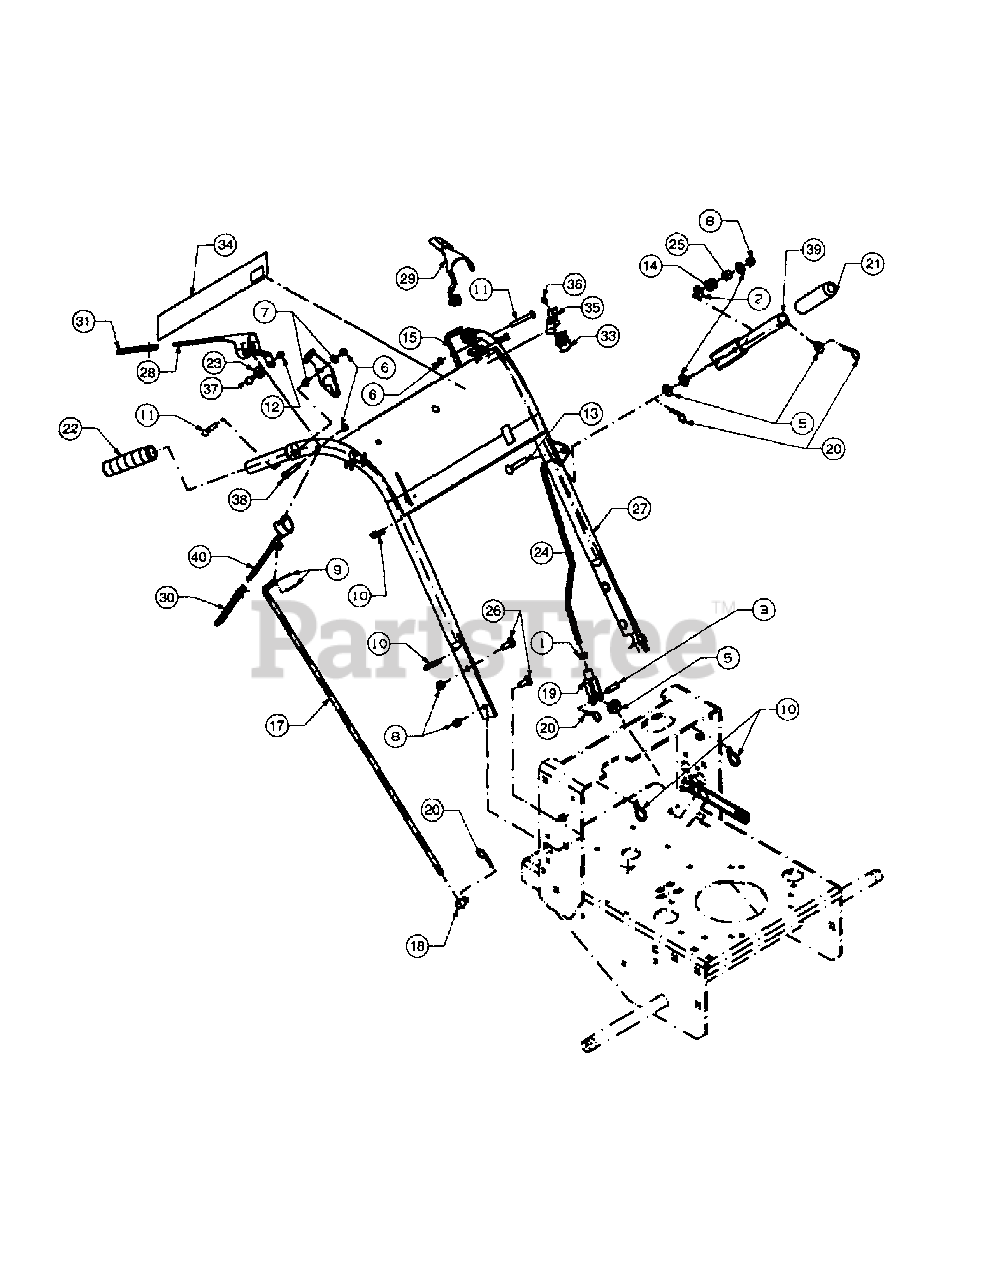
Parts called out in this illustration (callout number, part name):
1	Hex Nut, 3/8-16
2	Flat Washer, 3/8 Zinc
3	Clevis Pin, 3/8 x 1-1/8 Zinc
4	Grip, Neutral Latch, 1.25"
5	Flat Washer, 3/8 Zinc
6	Nylock Nut, 5/16-18
7	Flat Washer, 5/16 Zinc
8	Lock Nut, Nylon Insert, 3/8-16
9	Cotter Pin, 3/32 x 3/4, Zinc
10	Cable Tie, 3/16 x. 05 x 7.4
11	Hex Cap Screw, 5/16-18 x 2
12	Lock Nut, Nylon Insert
13	Carriage Bolt, 3/8-16 x 2
14	Spring, .850 OD x 1
15	Neutral Latch, Left Hand
15	Neutral Latch, Right Hand
17	Steering Control Rod
18	Joint Swivel
19	Yoke, 3/8-16 Female
20	Hair Pin 3/8-1/2
21	Handle Grip, Black, 1"
22	Plastic Handle Grip, Black, 4-5/8
23	Control Rod, Hydro Spacer
24	Hydro Blade Clutch Rod Base
25	Spring Sleeve
26	Carriage Bolt, 3/8-16 x 2
27	Handle Assembly Hydro
28	Operator Presence Control RH
29	Operator Presence Control LH
30	Control Sleeve, Black
31	Operator Control Sleeve, Yellow
32	Harness Assembly Adapter
33	Switch Mounting Snap
34	Handle Label, Rear, 5 Speed
35	Operator Presence Return Spring
36	Hex Index Washer Screw, 0.500
37	Shoulder Screw, .38 x .412, 1/4-28
38	Hex Cap Screw, 5/16-18, 2.00
39	Blade Clutch Lever
40	Lever Assembly Control
